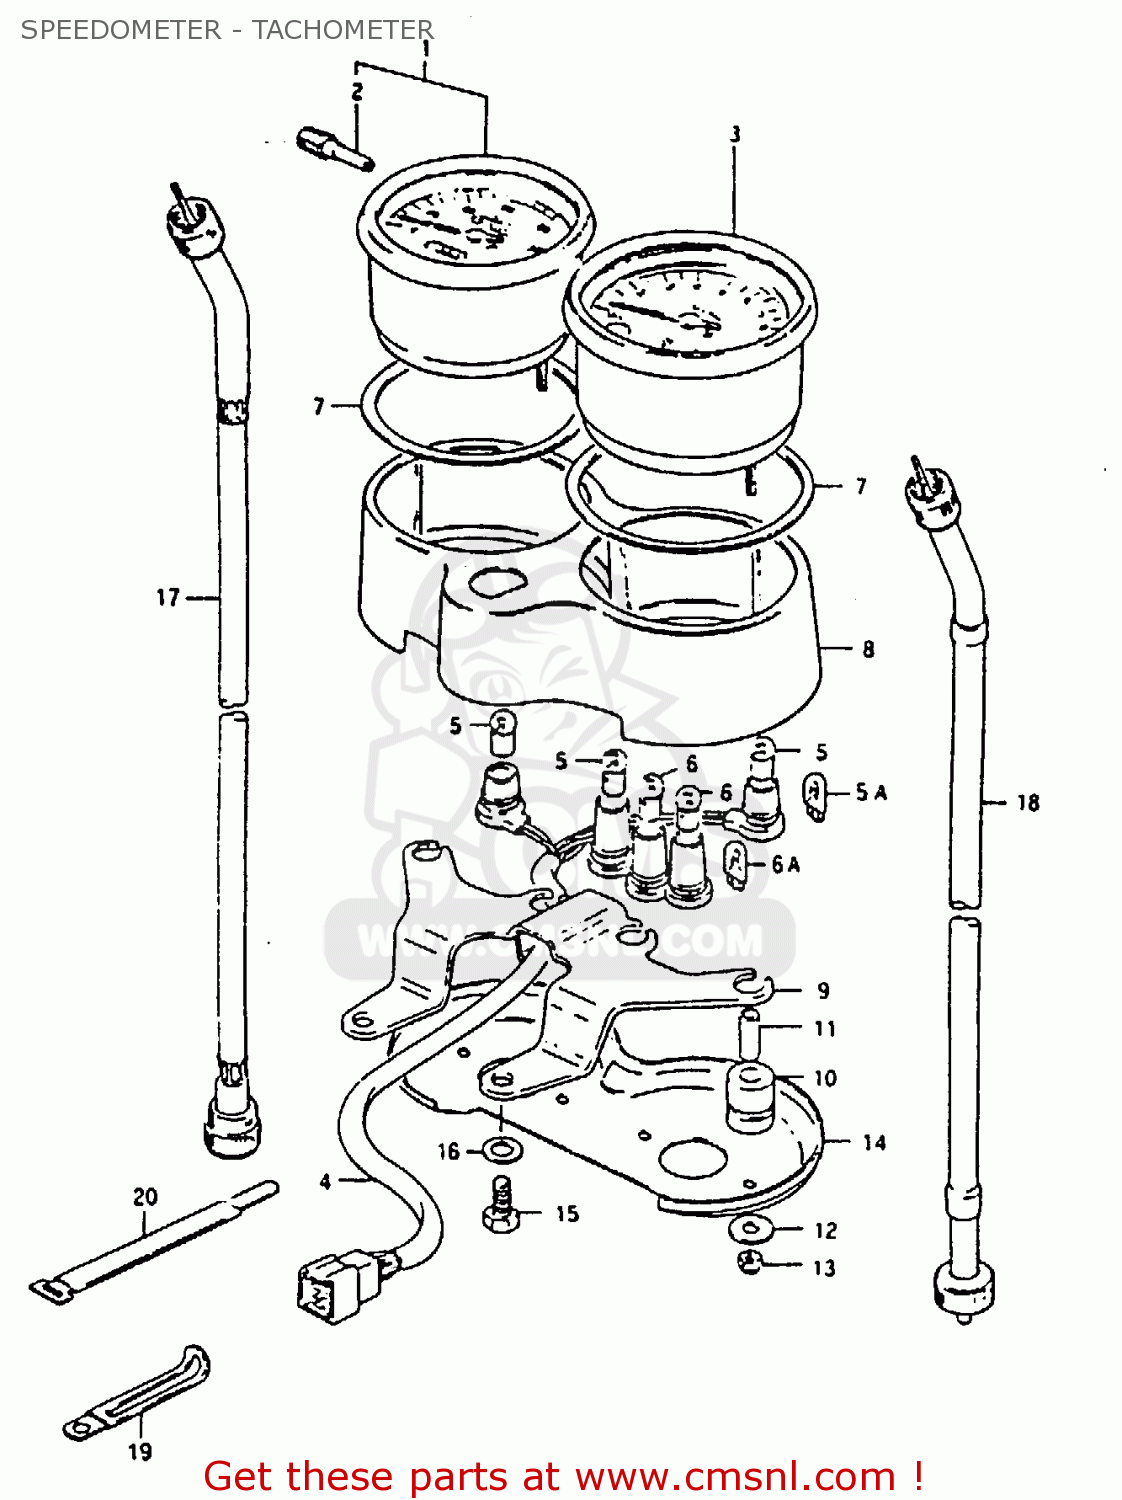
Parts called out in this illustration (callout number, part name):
1	SPEEDOMETER (KILO)
2	KNOB,TRIP METER
3	TACHOMETER
4	SOCKET
5	BULB(6V1.7W,STANLEY,A61A)
5A	BULB(6V1.7W,STANLEY,A61A)
6	BULB(6V/3W)
6A	BULB(6V,3W)
7	GASKET, METER
8	CASE, METER
9	BRACKET
10	CUSHION
11	SPACER
12	WASHER
13	NUT
14	UNDER PLATE
15	BOLT 8X12
16	WASHER
17	CABLE ASSY,SPEEDOMETER
18	CABLE ASSY,TACHOMETER
19	CLAMP
20	CLAMP L:110
